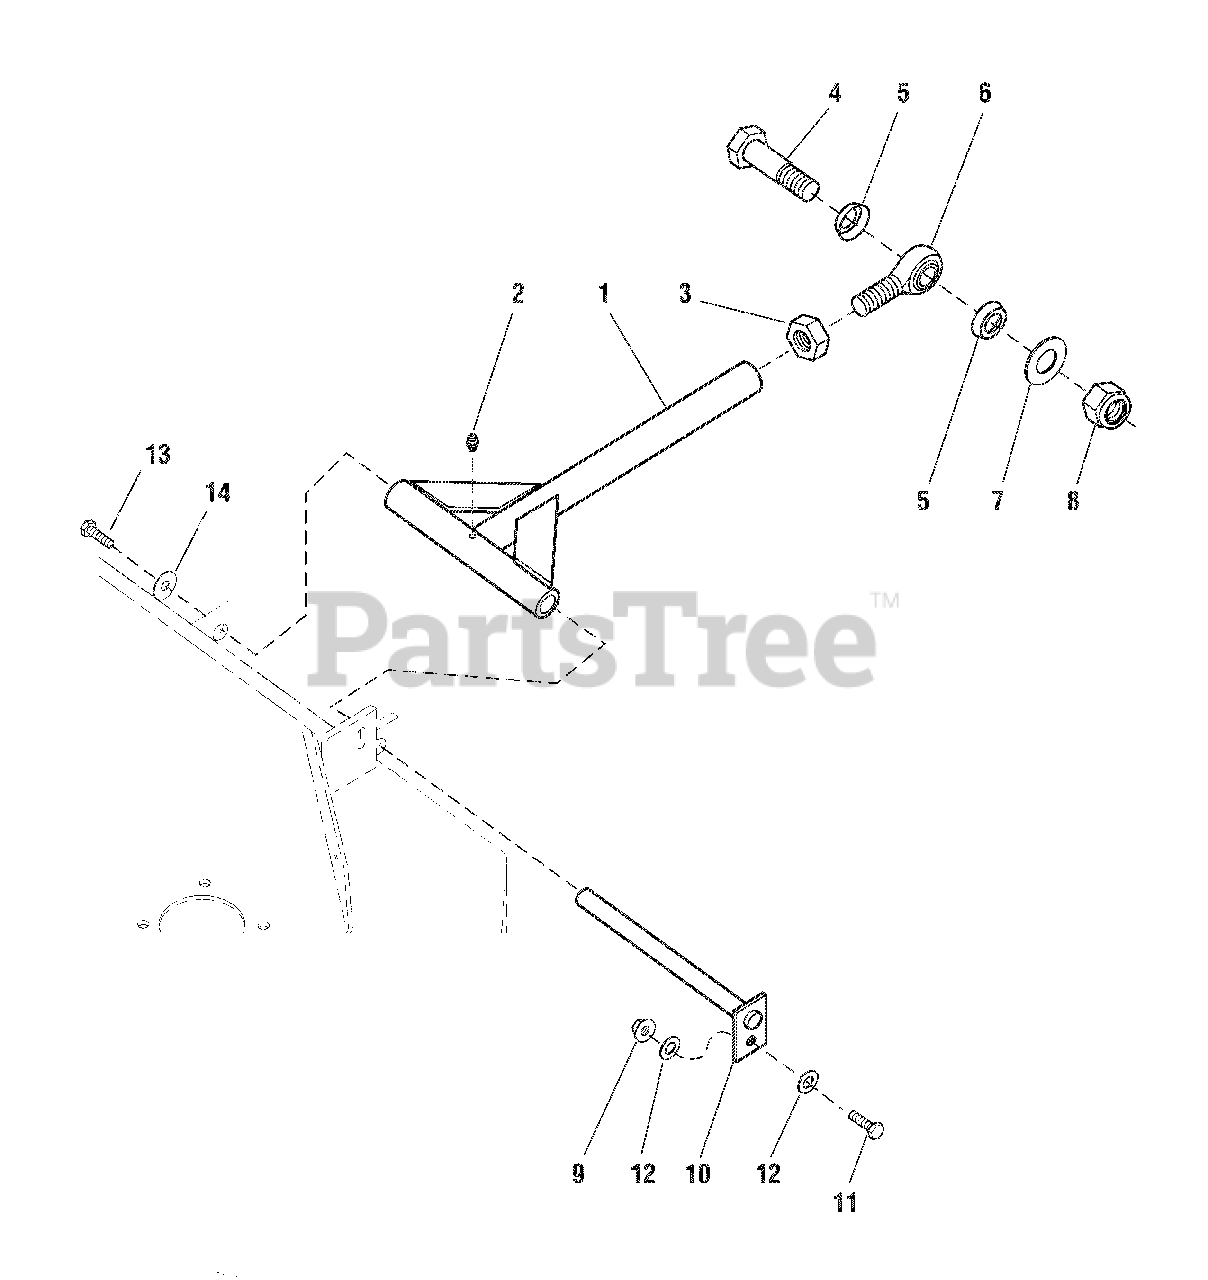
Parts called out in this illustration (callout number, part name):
1	PUSHER BAR ASSEMBLY
2	GREASE FITTING
3	NUT, Hex, Jam, 3/4-16
4	CAPSCREW, Hex Hd, 3/4-16 x 3
5	ROD END SEAL
6	BALL JOINT, 3/4-16
7	WASHER, 3/4
8	NUT, Hex, Nylon Lock, 3/4-16
9	NUT, Hex Nylon Lock, 3/8-16
10	WELD, DECK MOUNT SHAF
11	CAPSCREW, Hex Hd, 3/8-16 x 1-1/4
12	WASHER, 3/8
13	BOLT, 3/8-16 X 1 GD5 YZ
14	WASHER, .390 X 1.50 X .109 YZ
